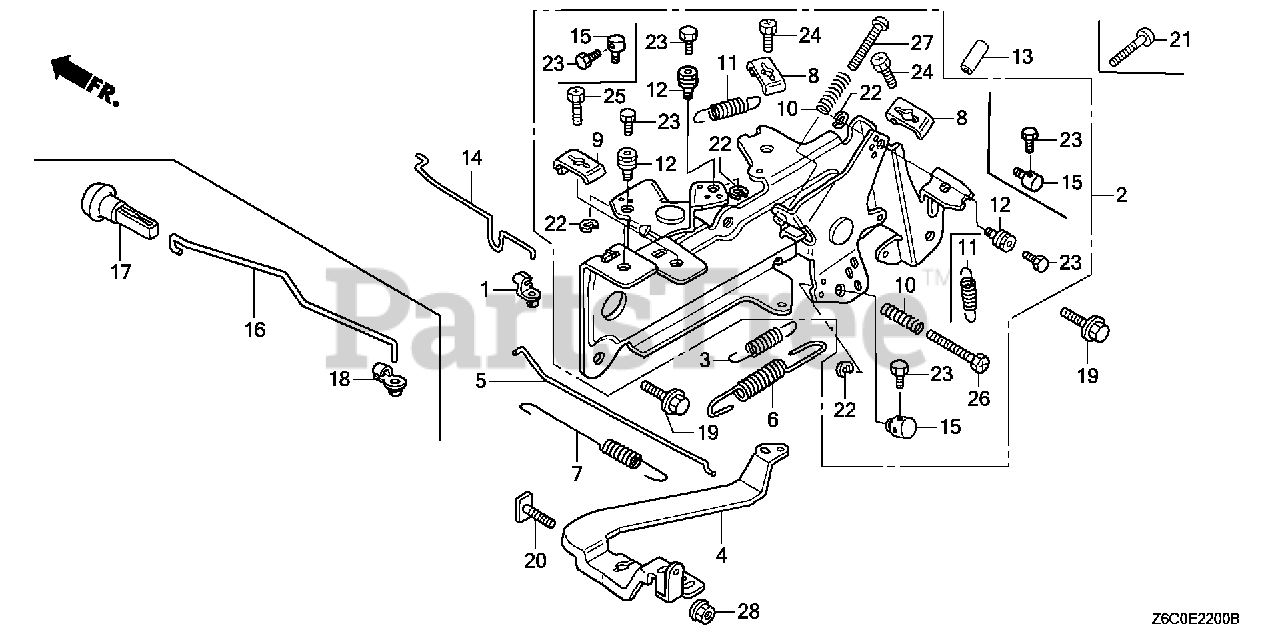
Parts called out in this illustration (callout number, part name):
1	JOINT, ROD
2	CONTROL ASSY.
3	SPRING, STARTER
4	ARM, GOVERNOR
5	ROD, GOVERNOR
6	SPRING, GOVERNOR
7	SPRING, THROTTLE RETURN
8	HOLDER, CABLE
10	SPRING, CONTROL ADJUSTING Use from Engine SN 2327377.
11	SPRING, CABLE RETURN
12	HOLDER, WIRE
14	ROD, CHOKE CONTROL
15	HOLDER, CABLE
19	BOLT, FLANGE (6X14)
20	BOLT, GOVERNOR ARM
22	CIRCLIP (5MM) Use from Engine SN 2327377.
23	BOLT, RECESSED (4X6)
24	BOLT, RECESSED (5X16)
26	BOLT, SLOT (5X25)
27	SCREW, PAN (5X25)
28	NUT, FLANGE (6MM)
